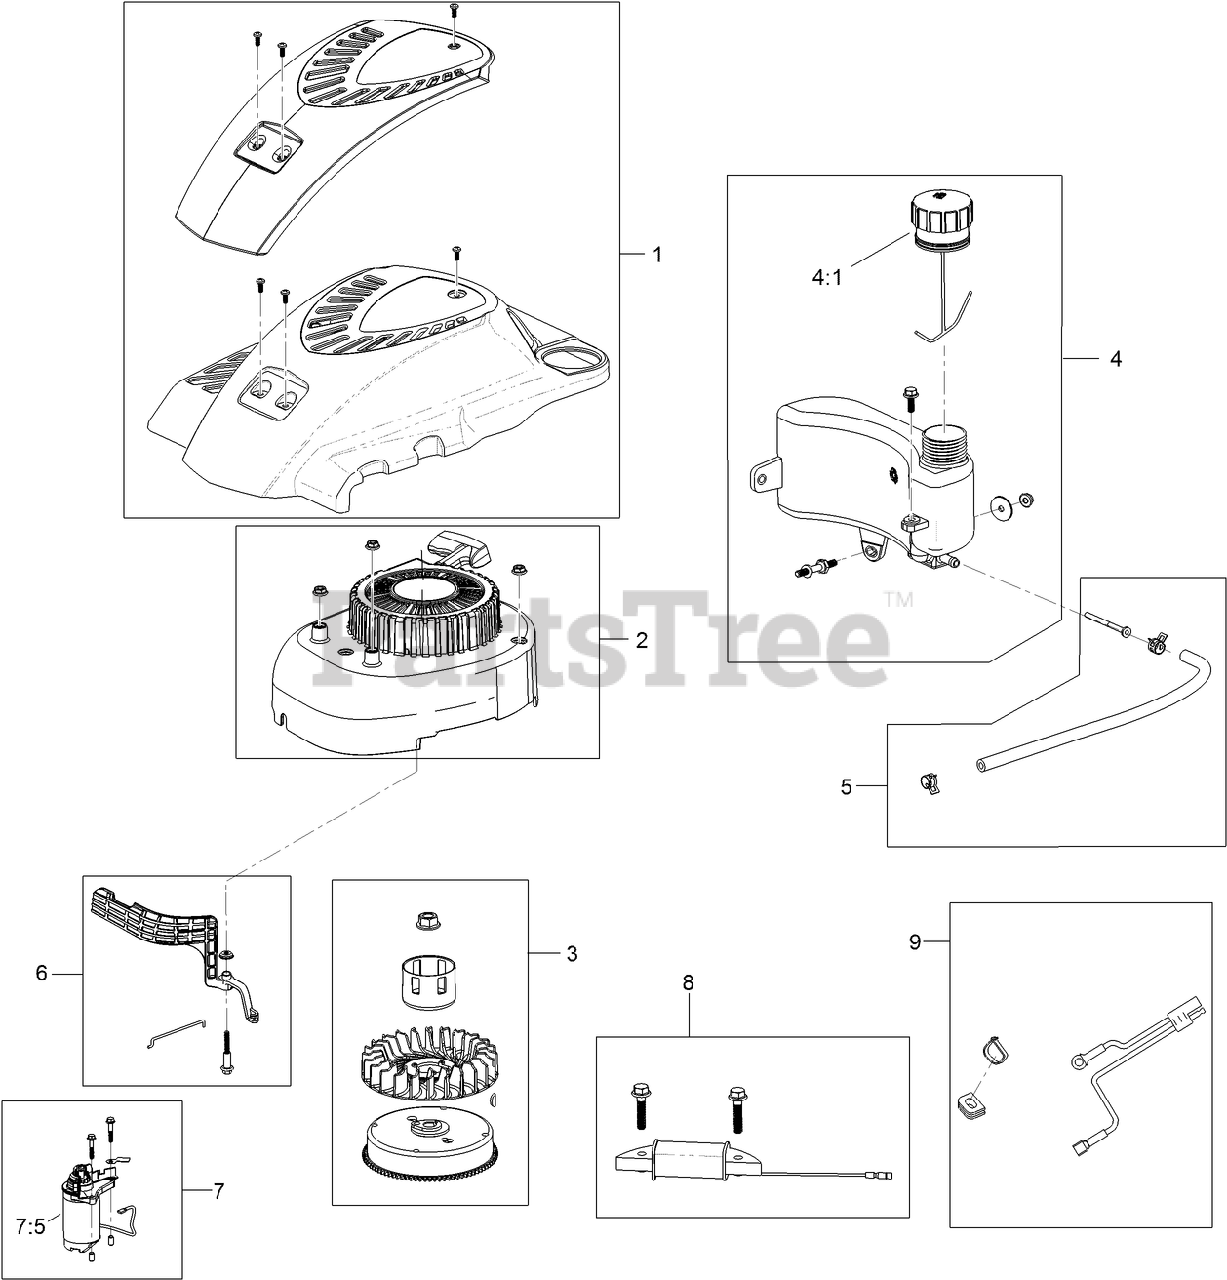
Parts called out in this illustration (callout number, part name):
1	SHROUD ASM
2	RECOIL AND BLOWER SHROUD KIT
3	FLYWHEEL AND FAN KIT
4	FUEL TANK KIT
4:1	CAP-FUEL
5	FUEL LINE KIT
6	AIR VANE KIT
7:5	MOTOR-STARTER
8	ALTERNATOR KIT
9	WIRE HARNESS KIT
